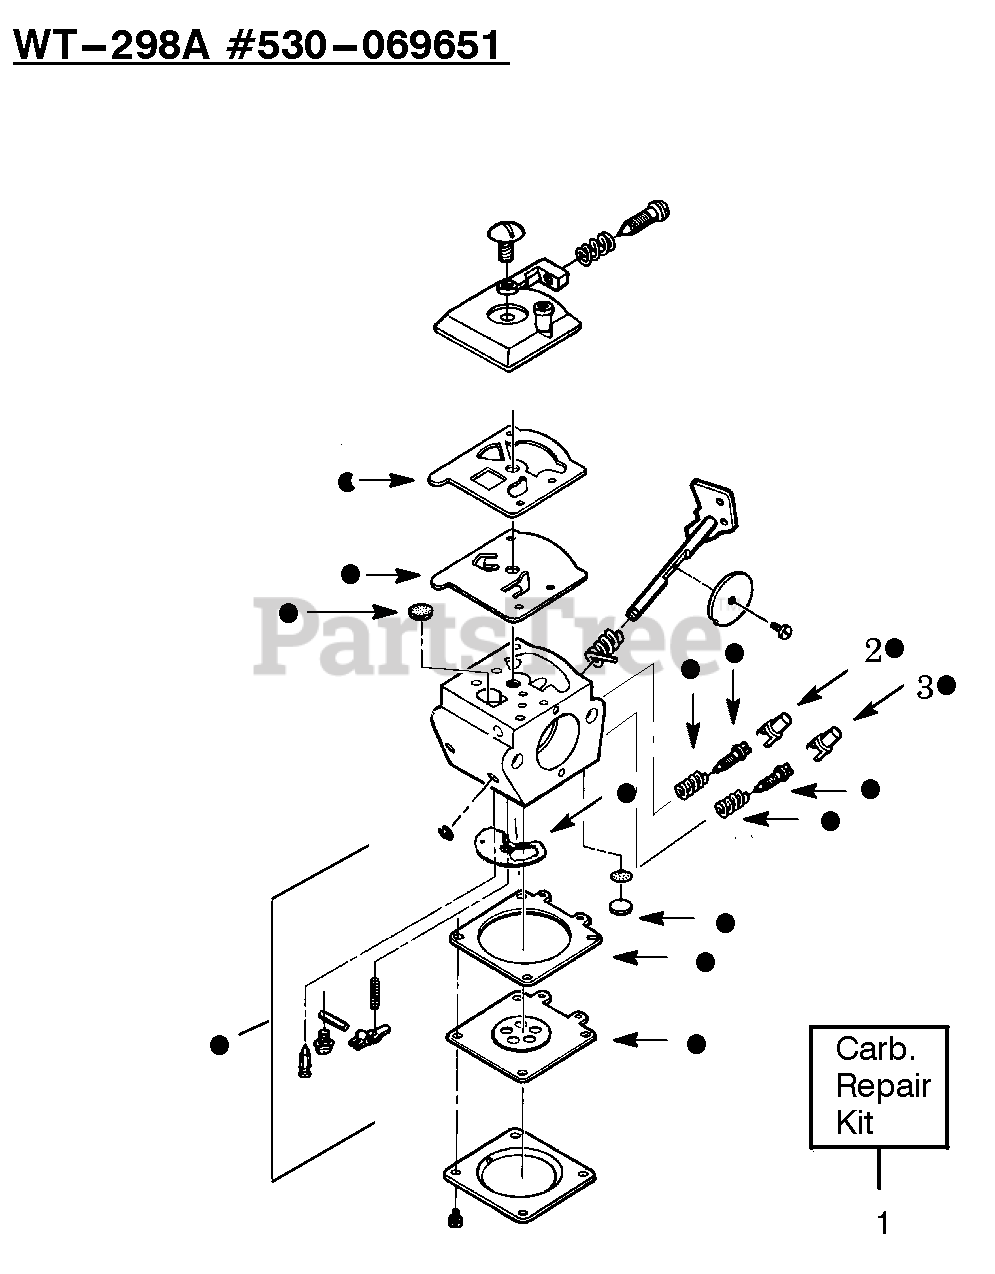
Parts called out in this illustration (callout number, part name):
1	Carburetor Repair Kit
2	Limiter Cap-Low
3	Limiter Cap-High
